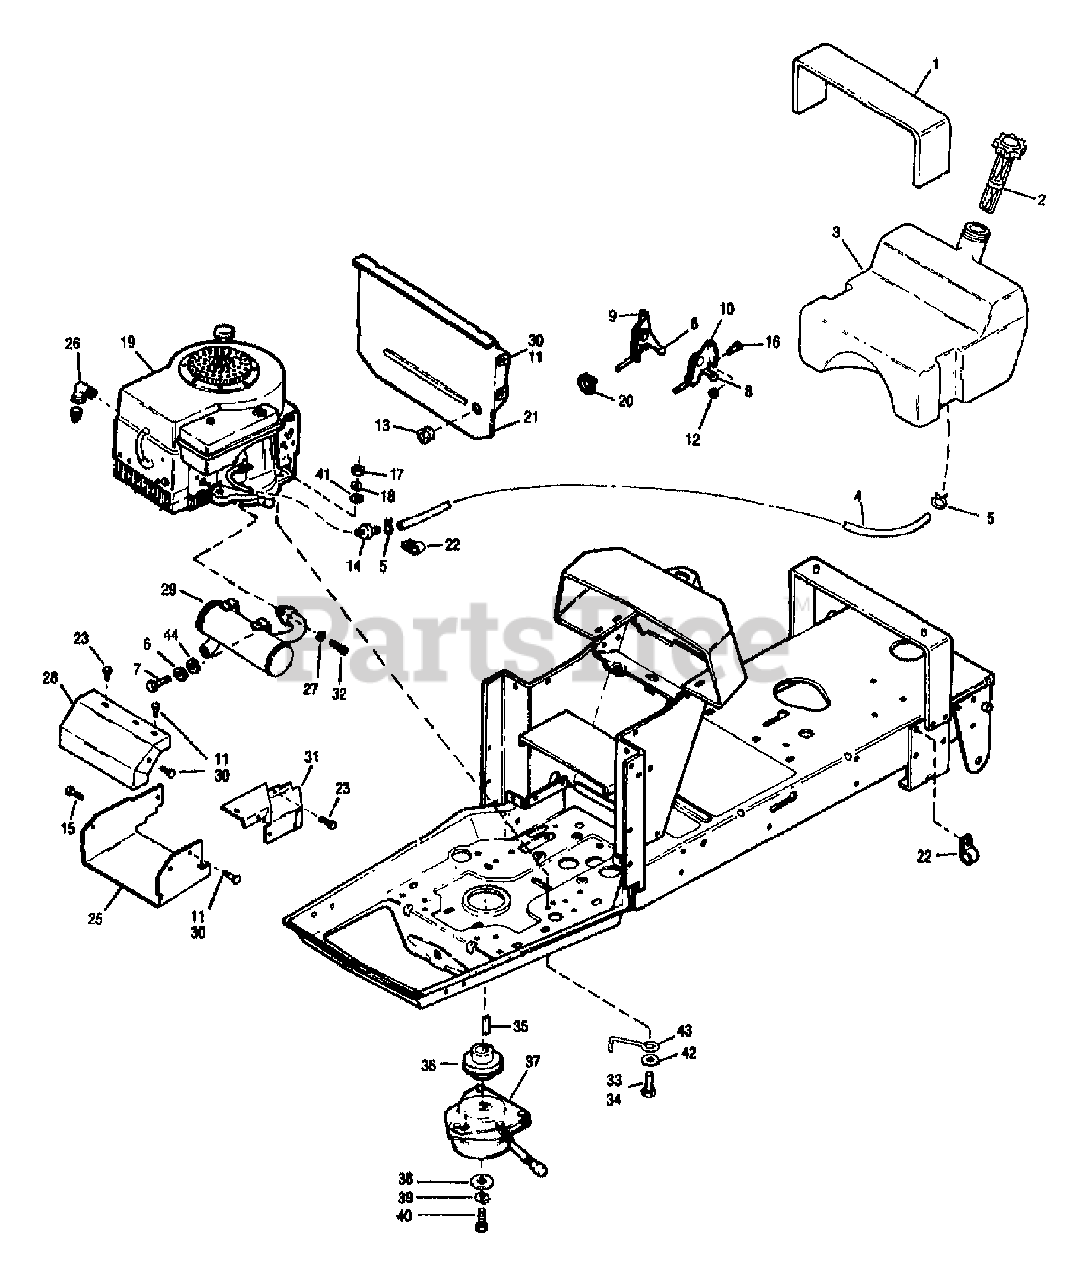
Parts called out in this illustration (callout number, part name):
1	PAD-FUEL TANK
2	CAP-GAS
3	TANK-FUEL
4	LINE-FUEL 52"
5	CLAMP-HOSE
8	KNOB
9	THROTTLE-CONTROL
10	C-CONTROL
13	GROMMET-SPLIT
14	FILTER-FUEL
15	SCR-LOCK
19	ENGINE, BRIGGS & STRATTON 12HP, MODEL 281707
20	TIE-CABLE NYLON BLACK
21	SHIELD-HEAT (RED) {3212GR}
21	SHIELD-HEAT (RED) {3312GR}
22	CLIP-J
23	SCR-HH 1/4-20X.625
25	SHIELD-HEAT
26	ELBOW-90 DEGREES
27	WASHER-LOCK
28	SHIELD-HEAT
30	NUT-SPEED #10
31	SHIELD-HEAT
32	SCR-HXSKT 5/16-18X.75 BO
35	KEY-.25 SQ X 1.25
36	SHEAVE
37	CLUTCH-ELECTRIC
38	WASHER-SPEC 1.42X.468X.25 ZP
40	SCR-HH 7/16-20X3 G5 ZP
43	CLUTCH-RETAINER
44	SPACER-.625X.344X.34
